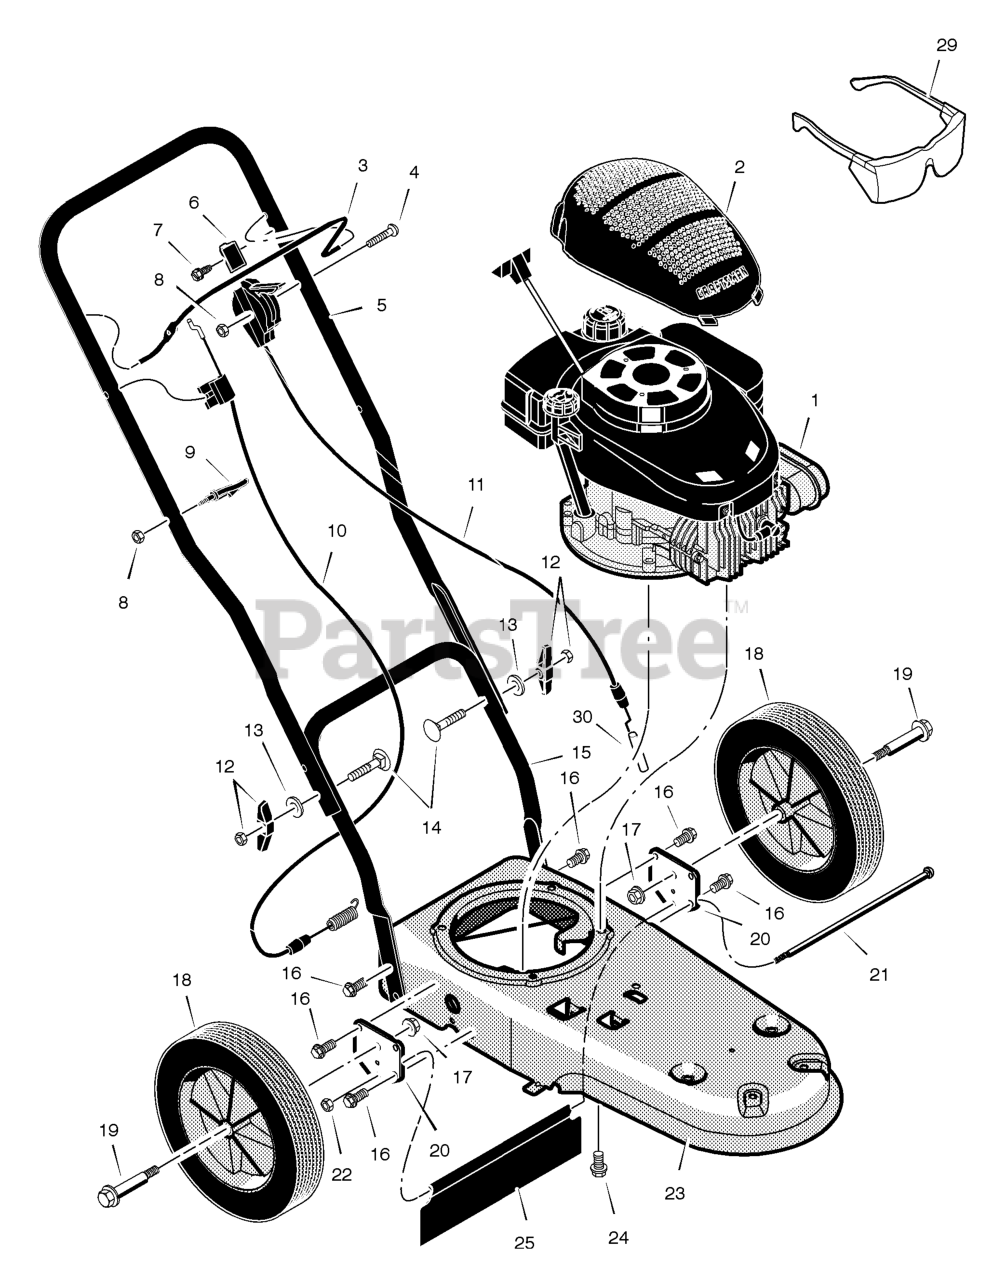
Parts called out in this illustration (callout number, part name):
1	Engine
2	Shroud, Engine
3	Lever, Control
5	Handle, Upper
6	Bracket, Stop
8	Nut
9	Guide, Rope
10	Cable, Drive
11	Control, Throttle
14	Bolt, Carriage
15	Handle, Lower
18	Wheel & Tire
19	Bolt, Axle
20	Bracket, Wheel
21	Rod, Rear Guard Bolt
22	Nut
23	Frame, Trimmer
25	Guard, Rear
29	Glasses, Safety
30	Spacer, Sleeve
